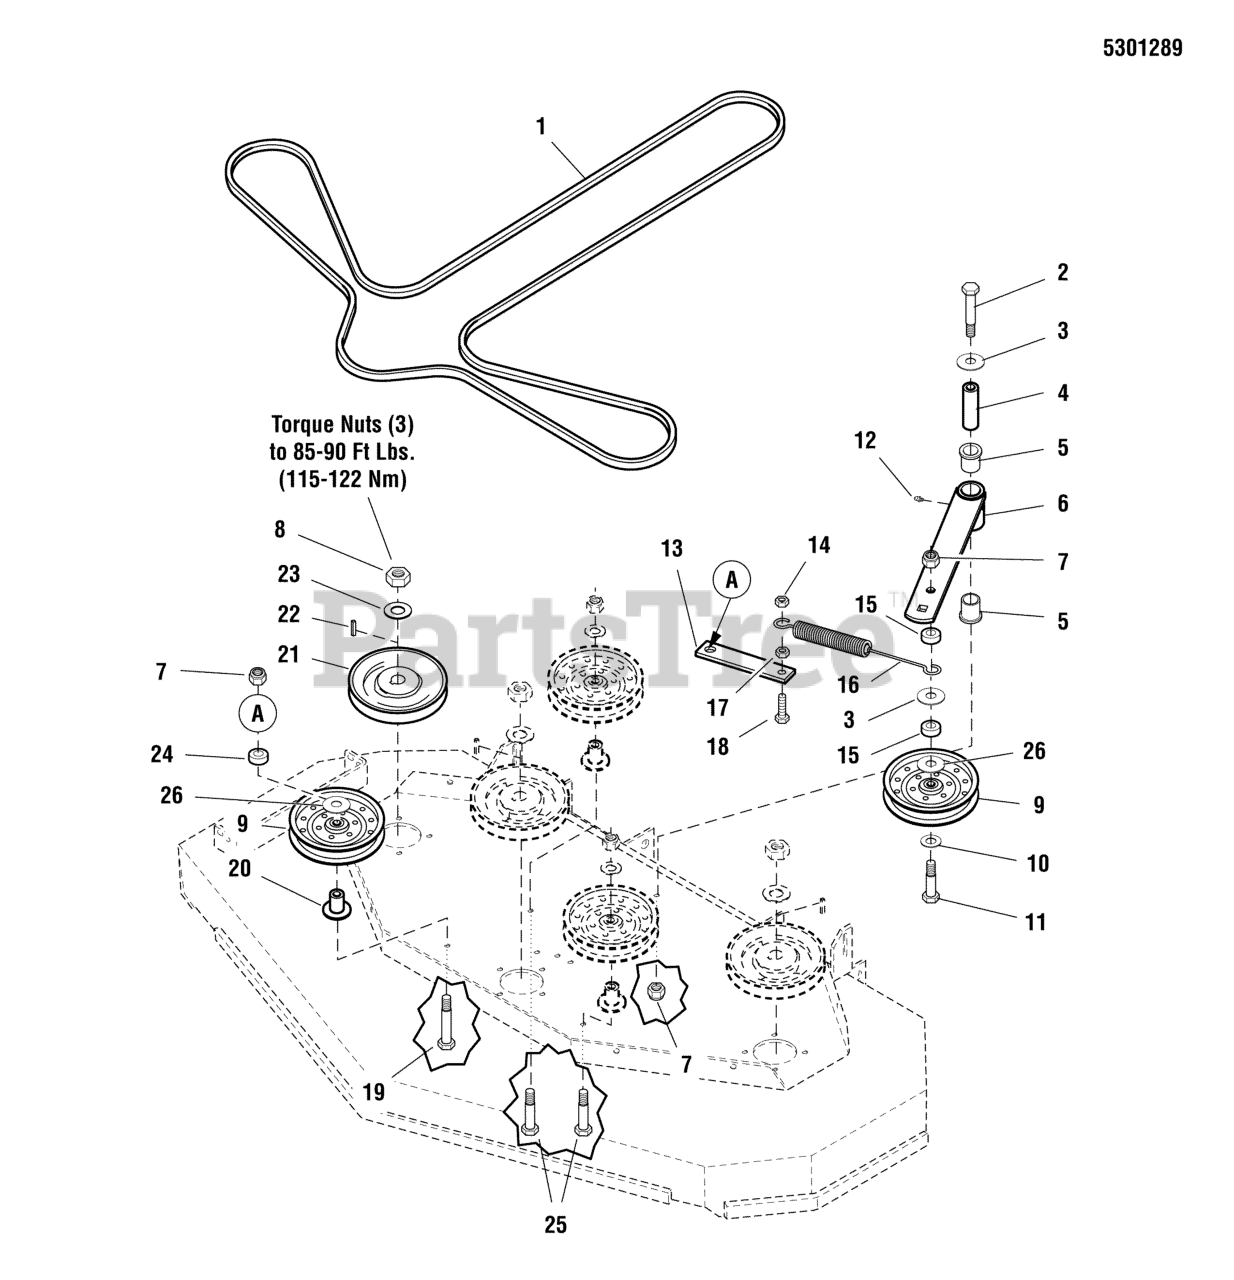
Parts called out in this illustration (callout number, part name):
1	BELT, 5V, 175.90EL, LG ARAMID, WRPD, RC
2	BOLT, 1/2-13 X 4-1/2 GD5
3	WASHER, 1/2 USS
4	SPACER, .52 X 1.00 X 3.50
5	BUSHING, FLANGE
6	ASSM, IDLER ARM
7	NUT, Hex Flange, Nylock, 1/2-13
8	NUT, 3/4-16 HEX
10	WASHER, 1/2 GD9 YZ
11	BOLT, 1/2-13 X 2-3/4 GD5 CZ
12	GREASE FITTING, 1/4-28 STRAIGHT
13	MOUNT, IDLER SPRING - RED
14	NUT, 3/8-16 HEX SIDE LOCK
15	SPACER, .52 X 1.00 X .38
16	SPRING-EXTENSION, SWIVEL END
17	NUT, 3/8-16 HEX SERRATED FLANGE
18	BOLT, 3/8-16 X 1-1/4" GD5 CZ
19	BOLT, 1/2-13 X 3-1/2, HEX HD, GD5, CZ (SV)
20	IDLER MOUNT
21	PULLEY, 6.93 EOD X 25MM, SPLIT
22	KEY, 1/4 SQ. X 1-1/4
23	WASHER, 3/4 BELLEVILLE
24	SPACER, .52 X 1.00 X .44
25	BOLT, 1/2-13 X 3" GD5 CZ
26	SHIELD, PULLEY BEARING
